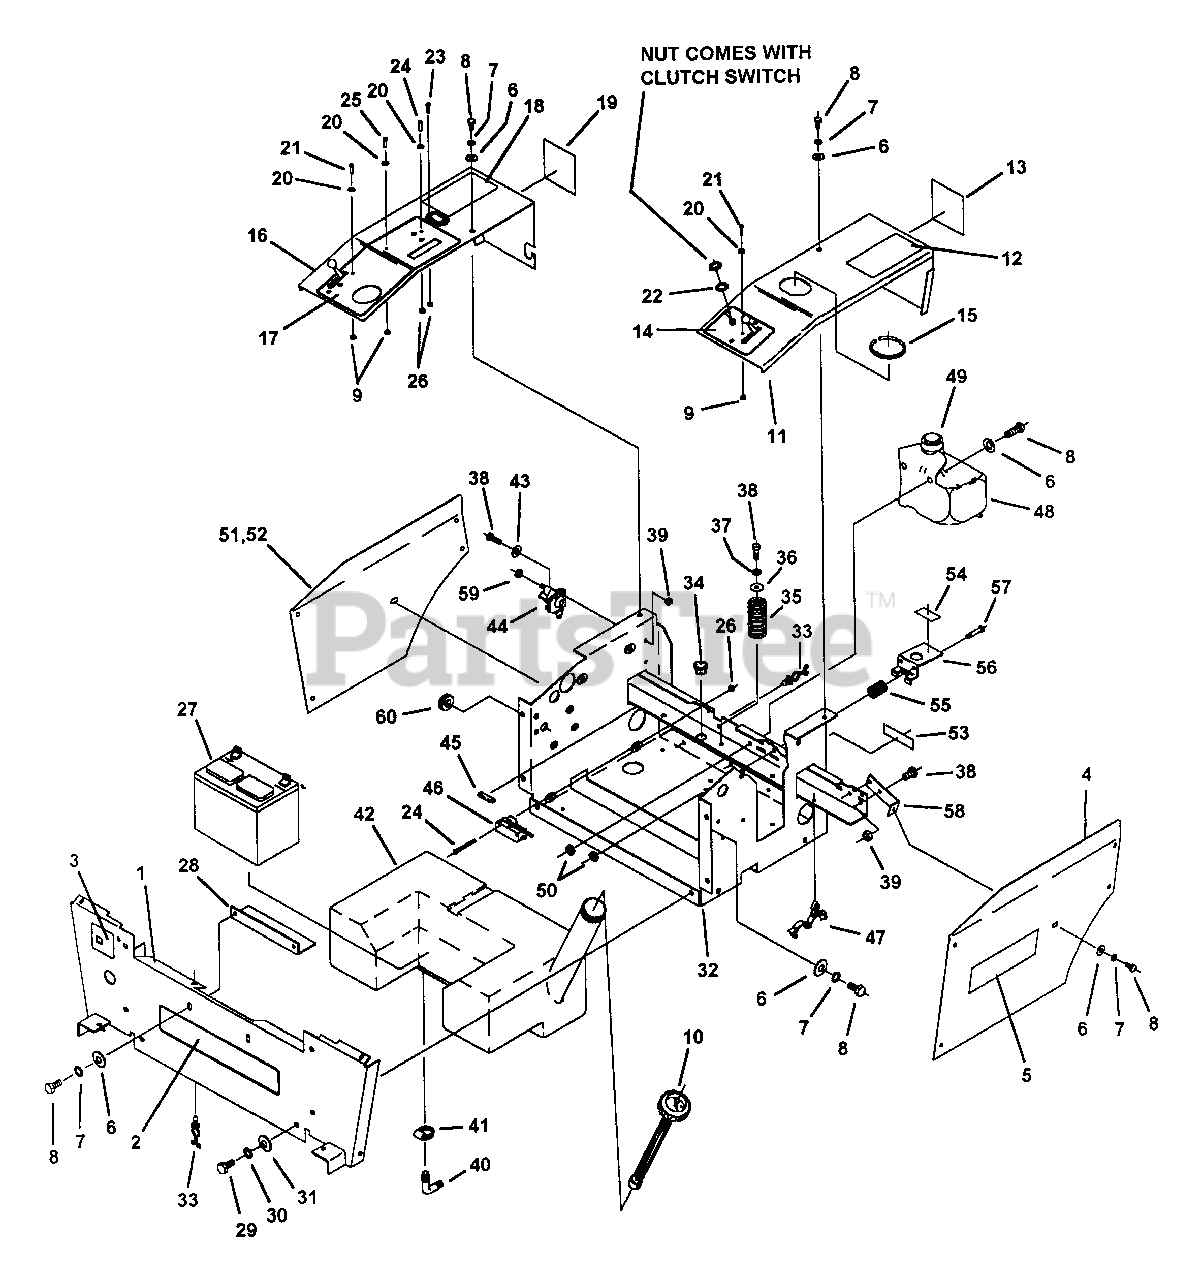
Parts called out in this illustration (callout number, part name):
1	SEAT SUPPORT FRONT ASSEMBLY (w/decals)
2	DECAL, SNAPPER
3	DECAL, START SWITCH
4	FENDER SKIRT, LH
5	DECAL, I.D. "Z1404K" 14 HP MODEL
5	DECAL, I.D. "Z1804K" 18 HP MODEL
5	DECAL, I.D. "Z2004K" 20 HP MODEL
6	WASHER, FLAT STD. 5/16"
7	LOCKWASHER, 5/16" HEAVY SPRING
8	BOLT, 5/16-18 X 3/4" GR. 5
9	LOCKNUT, #8-32 NYLOC
10	FUEL GAUGE CAP
11	FENDER CAP (w/decals) LH
12	DECAL, CAUTION
13	DECAL, TOWING WARNING
14	DECAL, BLADE/CHOKE
15	TRIM, U-CHANNEL GAS TANK
16	FENDER CAP (w/decals) RH
17	DECAL, INSTRUMENT PANEL
18	DECAL, CAUTION
19	DECAL, BELT TENSIONING
20	WASHER, #8 FLAT
21	SCREW, MACHINE, #8-32 X 1/2"
22	D-WASHER
23	SCREW, MACHINE, #6-32 X 5/8"
24	SCREW, MACHINE, #6-32 X 1"
25	SCREW, MACHINE, #8-32 X 3/4"
26	LOCKNUT, #6-32 NYLOC
27	BATTERY 12 VOLT
28	BATTERY CLAMP ANGLE
29	BOLT, 3/8-16 X 3/4" GR. 5
30	LOCKWASHER, 3/8" HEAVY SPRING
31	WASHER,FLAT STD. 3/8"
32	SEAT SUPPORT WELDMENT
33	BLIND HOLE KURLY
34	BUSHING, PLASTIC
35	SEAT SPRING
37	LOCKWASHER, 1/4" SPLIT SPRING
38	BOLT, 1/4-20 X 3/4" GR. 5
39	LOCKNUT, 1/4-20 NYLOC
40	ELBOW, 90D 1/4NPT X 1/4 BARB
41	CLAMP, .31 MIN. X .87 MAX. HOSE DIA.
42	FUEL TANK
43	WASHER, FLAT STD. 1/4"
44	SOLENOID, 12V STARTER
45	EDGE GUARD
46	SWITCH, ENCL, SPDT 15A HINGED LEVER
47	FITTING 1/2" ROSE BUD CLIP
48	TANK, 1.5 QT. CHARGE PUMP
49	CAP, OIL TANK
50	NUT, HEX. 5/16-18 NYLOC
51	FENDER SKIRT, RH
52	DECAL, I.D. "Z1404K" 14 HP MODEL
52	DECAL, I.D. "Z1804K" 18 HP MODEL
52	DECAL, I.D. "Z2004K" 20 HP MODEL
53	DECAL, MOBIL 1, OIL
54	DECAL, "PULL TO RELEASE..."
55	SPRING, COMPRESSION, .5 O.D. X.625 X.65
56	LATCH PLATE
57	BOLT, 5/16-18 X 1-3/4" GR.5
58	SKIRT BRACKET, FENDER
59	NUT, 5/16-24 UNF, GR. 5 PLATED
60	GROMMET, RUBBER LAVELLE #917
